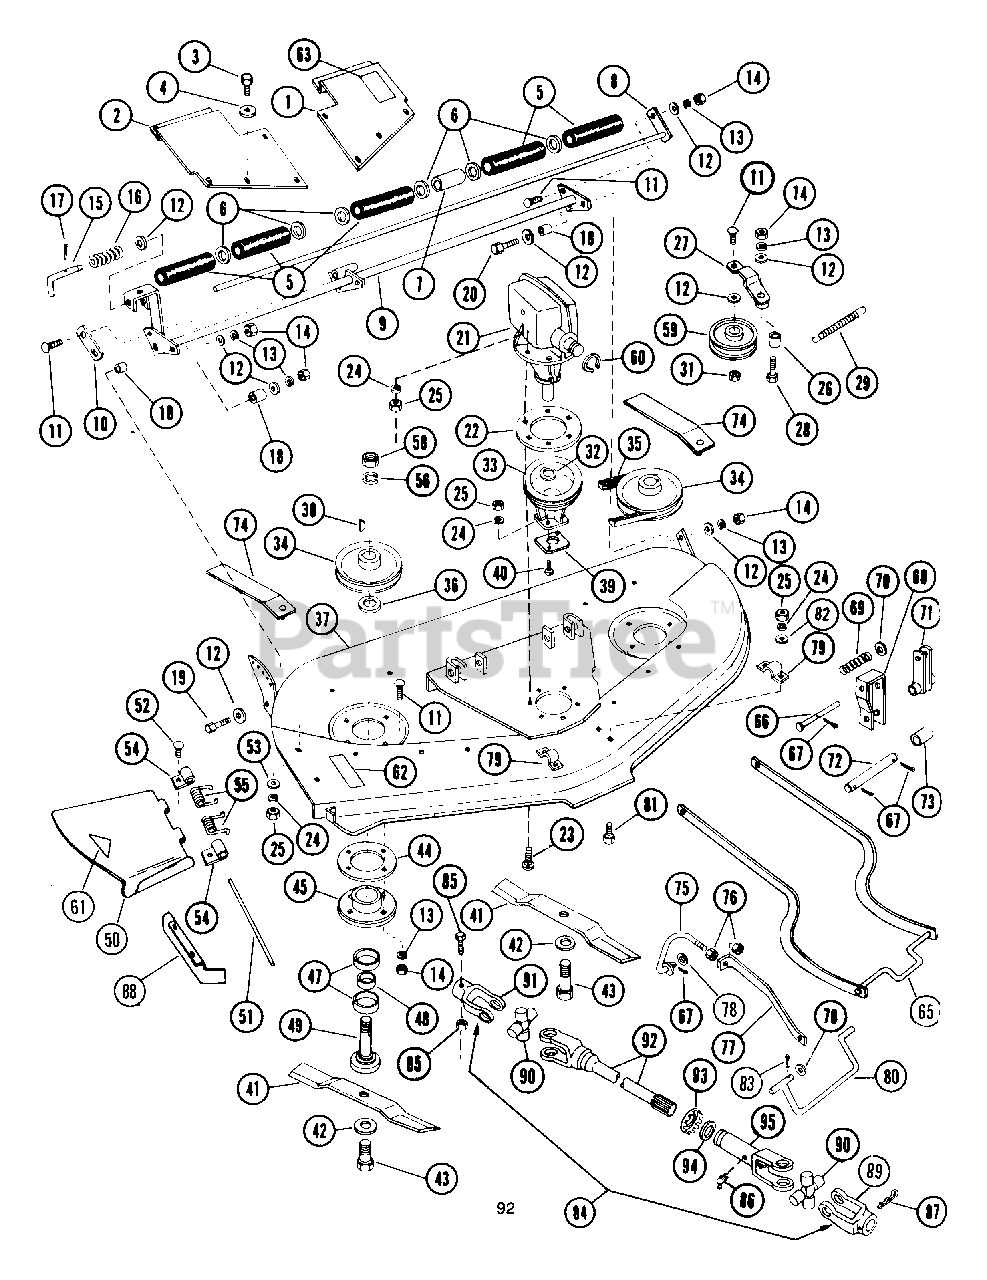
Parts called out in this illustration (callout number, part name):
1	SHIELD ASSEMBLY
2	R.H. BELT SHIELD
3	SCR-TAP .250-20X.50 HH F
4	WSHR-FL-STL.281X.62X.065 PL
6	WSHR-FL-STL.656X1.312X.095 PL
7	SPACER .692X.812X2.125
8	ROLLER SHAFT
9	ROLLER ADJUSTMENT
11	BLT-RDHDSQNK .38-16X1.0 PL
12	WSHR-FL-STL .438X1.0X.083 PL
13	WSHR-LK .375X.094 MED PL
14	NUT-HEX .375-16
16	SG-COMP .063X.63X1.75 WLD10
17	PIN-COTR .12X.75 PL
18	SPACER BUSHING
19	BLT-HEX .38-16X1.25 PL GR 2
20	BLT-HEX .38-16X1.00 PL
21	GEARBOX ASSEMBLY
23	BLT-RDHDSQNK .31-18X.75 SHT PL
24	WSHR-LK .312X.097 PL HVY
25	NUT-HEX .312-18
26	BSHG-SLV .375X.625X.1.000
27	IDLER ARM
28	BLT-HEX .38-16X1.75 PL GR2
29	SG-TENS .125X.812X5.25 WLD 15
31	NUT-LK-JAM-CTR .375-16 PL
32	WSHR-FL-STL .781X1.500X.060
34	PLY-V 4.50 X .75 W/KEY SALEM
35	V-BELT, HA-WRAPPED
36	WSHR-FL-STL .781X1.250X.059 PL
37	DECK ASSEMBLY
38	KEY-WDRF .188X.75X.313 SAE 9
40	SCR-MCH .31-18X1.00 SLFL PL
42	BELLEVILLE WASHER
43	BLT-HEX .44-20X1.00 GR5
45	FLANGED BEARING HOUSING
47	BRG-BALL .750X1.781X.61
48	SPACER .807X1.001X.445
49	SPINDLE SHAFT
50	CHUTE EXTENSION
51	CHUTE PIVOT ROD
52	BLT-RDHDSQNK .312-18X.62SHTPL
53	WSHR-FL-STL .38X.875X.083 PL
54	CHUTE HINGE
55	SG-TORS .080X.28X1.30
56	WSHR-LK-INT .750X.050 MED
58	NUT-JAM .75-16 PL
59	IDLER-FLAT 3.00 X .38 CLK.&CAP
60	RG-RTNG-EXT .750X.078
61	SAFETY LABEL
62	DECAL ROTATING PARTS
63	DECAL CAUTION
65	MOWER HANGER
66	SPACER .379X.625X.500
67	PIN-COTR .12X1.0 PL
68	SUPPORT CHANNEL
69	SG-COMP .62X.68X1.75
70	WSHR-FL-STL .531X1.062X.095 PL
72	PIN-CLEV .498X4.31 YWZC
73	SPACER .516X.749X.938
74	RAMP
75	ADJUSTING ROD
76	NUT .50-13 PL
78	WSHR-FL-STL.563X1.37X.109PL
80	SUPPORT SHAFT
81	BLT-RDHDSQNK .31-18X.75 GR5 PL
82	WSHR-FL-STL.344X.688X.065PL
83	PIN-COTR .25X1.50 ST PL
84	P.T.O. SHAFT ASSEMBLY
85	BLT-HEX .25-20X2.13 GR5
86	SPIN DRIVE ZERK FITTING
87	PIN-HAIR INT .18X1.18X3.25 PL
88	ELEC START KIT-USA TEC #1133-1
90	JOURNAL CROSS & BEARING ASSEMB
92	YOKE & SHAFT
93	RETAINER CAP
94	GREASE SEAL
